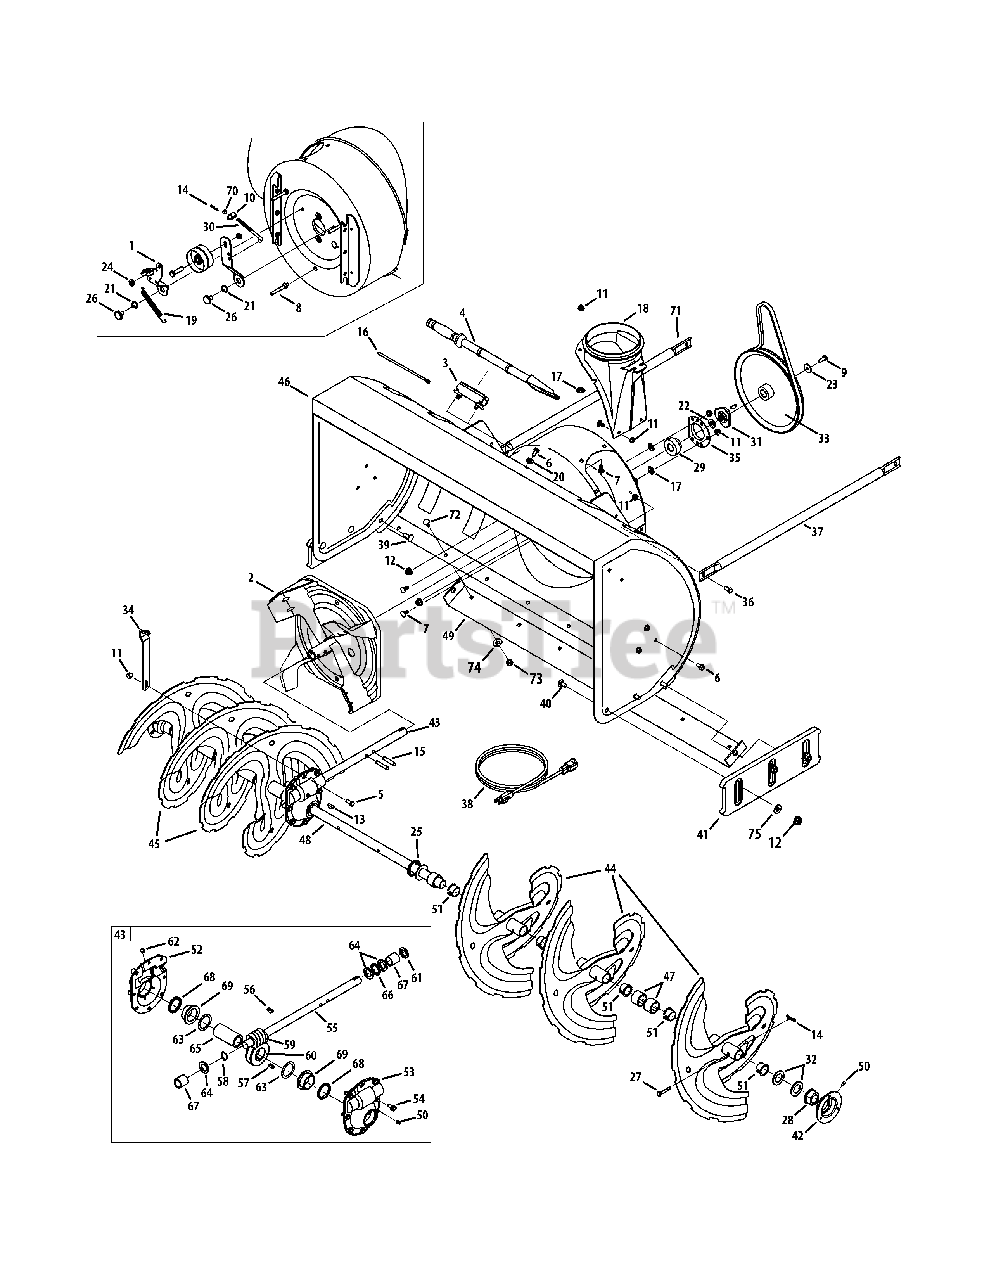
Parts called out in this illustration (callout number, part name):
1	Bracket Assembly, Auger Brake
2	Impeller , 16"
3	Clip, Mounting
4	Tool, Clean-out
5	Screw, Hex Cap, 5/16-18 x 1.0 Gr5
6	Screw, 5/16-18 x .750
7	Screw, Carriage, 5/16-18 x .75
8	Screw w/Stud, 5/16-18 x .4300
9	Screw, Hex Cap Lock, 5/16-24, 875
11	Nut, Hex Flange Lock, 5/16-18
12	Nut, Hex Flange Lock, 3/8-16
13	Key, Woodruff, 1/4 x 3/4
14	Pin, Bow-tie Cotter
15	Pin, Spiral, 5/16 x 1.75
16	Cable Tie
17	Nut, Push
18	Adapter, Chute, 6"
19	Spring, Extension
20	Washer, Flat, .349 x .879 .063
21	Washer, Wave, .625 x .885 x .015
22	Washer, Bell., .78 x 1.49 x .06
23	Washer, Flat, .34 x 1.5 x .15 Ht.
24	Washer, .344 x .75 x .12
25	Washer, 1.01 x 1.86 x .06
26	Screw, Shoulder, .625 x .17
27	Pin, Shear, .25 x 1.75
28	Bearing, Flange w/Flats
29	Bearing, Self Aligning
30	Rod, Auger Idler
31	Adapter, Pulley w/Pins
32	Spacer, 1.004 x 1.375 x .25
33	Pulley, Auger Drive, 10.0
34	Bracket, Gear Box Support
35	Housing, Bearing
36	Screw, 5/16-18 x .75 GR5
37	Tube, Support , LH
38	Extension Cord, 110V
39	Screw, Carriage, 3/8-16 x .75
40	Screw, Carriage, 3/8-16 x 1.00
42	Housing, Bearing
43	Gear Box Assembly
44	Spiral Assembly, LH
45	Spiral Assembly, RH
46	Housing, Auger - 45"
47	Spacer, 1.50 x 1.00 x 1.00
48	Axle, Spiral
49	Shave Plate, 45"
50	Grease Fitting, 3/16
51	Flange Bushing
52	Housing Assembly, Auger, RH
53	Housing Assembly, Auger, LH
54	Screw, LD, 5/16-18 x .750
55	Auger Drive Shaft
56	Key, Hi Pro, 3/16 x 3/4
57	Key, 1/4 x 3/4 Dia.
58	External Retainer Ring
59	Gear, Worm
60	Gear, Worm, LH
61	Seal, Oil
63	Wash, Flat, 1.52ID x 2.0 OD
64	Wash, Flat, .88 ID x .38 OD
65	Worm Gear Shaft
66	Bearing, Thrust
69	Flange Bearing
70	Jam Nut, 5/16-18
71	Tube, Support, RH
72	Screw, Carriage, 5/16-18 x .750
73	Nut, Hex, 5/16-18
74	Washer, Bell., .34 x .872 x .060
75	Washer, Flat, .385 x .870 x .092
